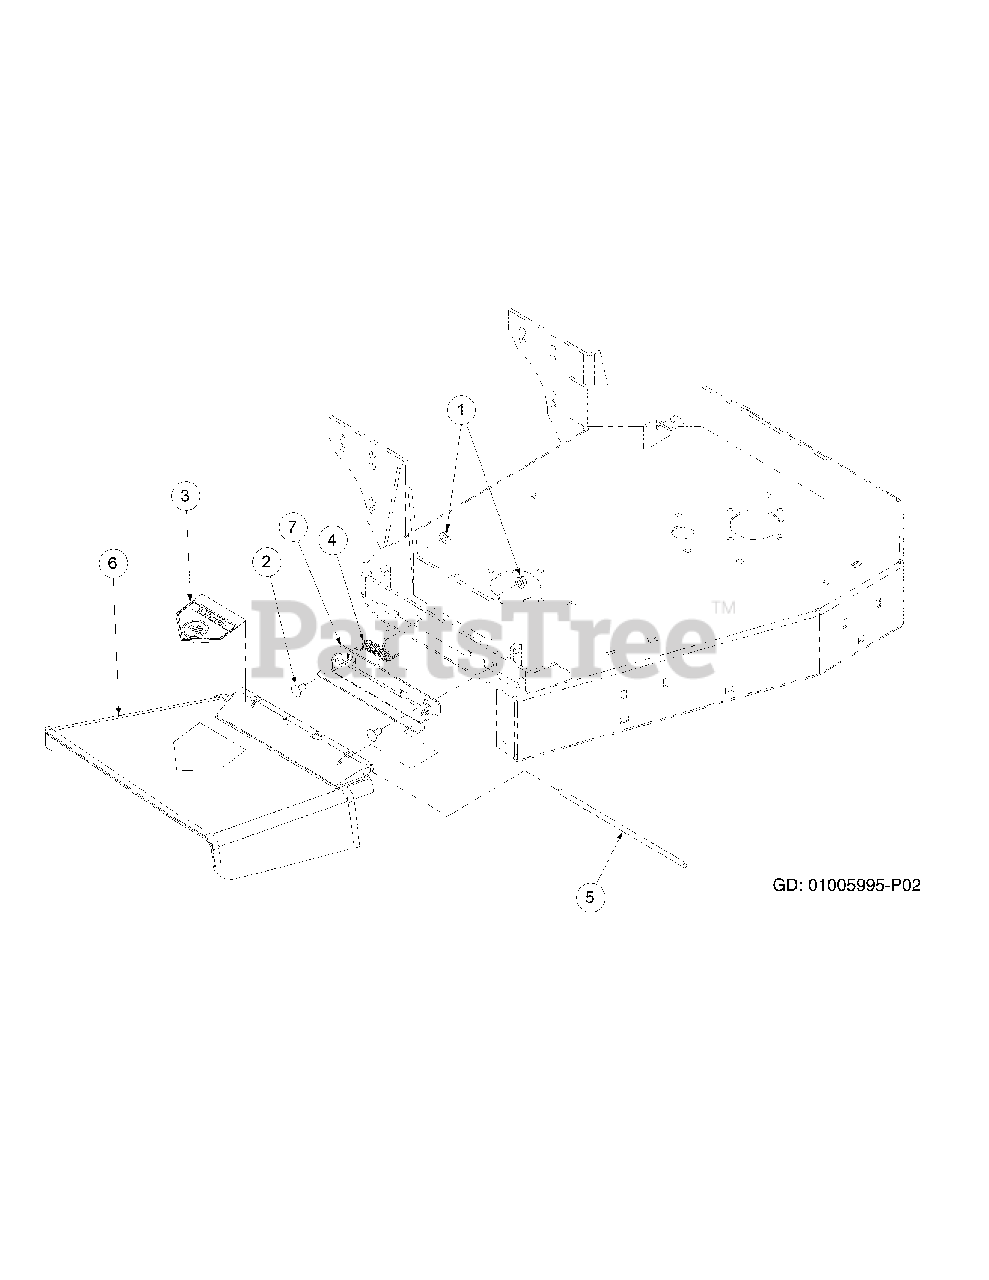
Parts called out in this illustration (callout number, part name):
1	Hex Nut Flange Lock, 3/8-16
2	Carriage Bolt, 3/8-16 x .75 LG.
3	Decal, Danger Hands & Feet
4	Torsion Spring, 0.4 ID x 2.16 LG
5	Chute Deflector Rod
6	Deflector Chute
7	Deflector Chute Bracket
